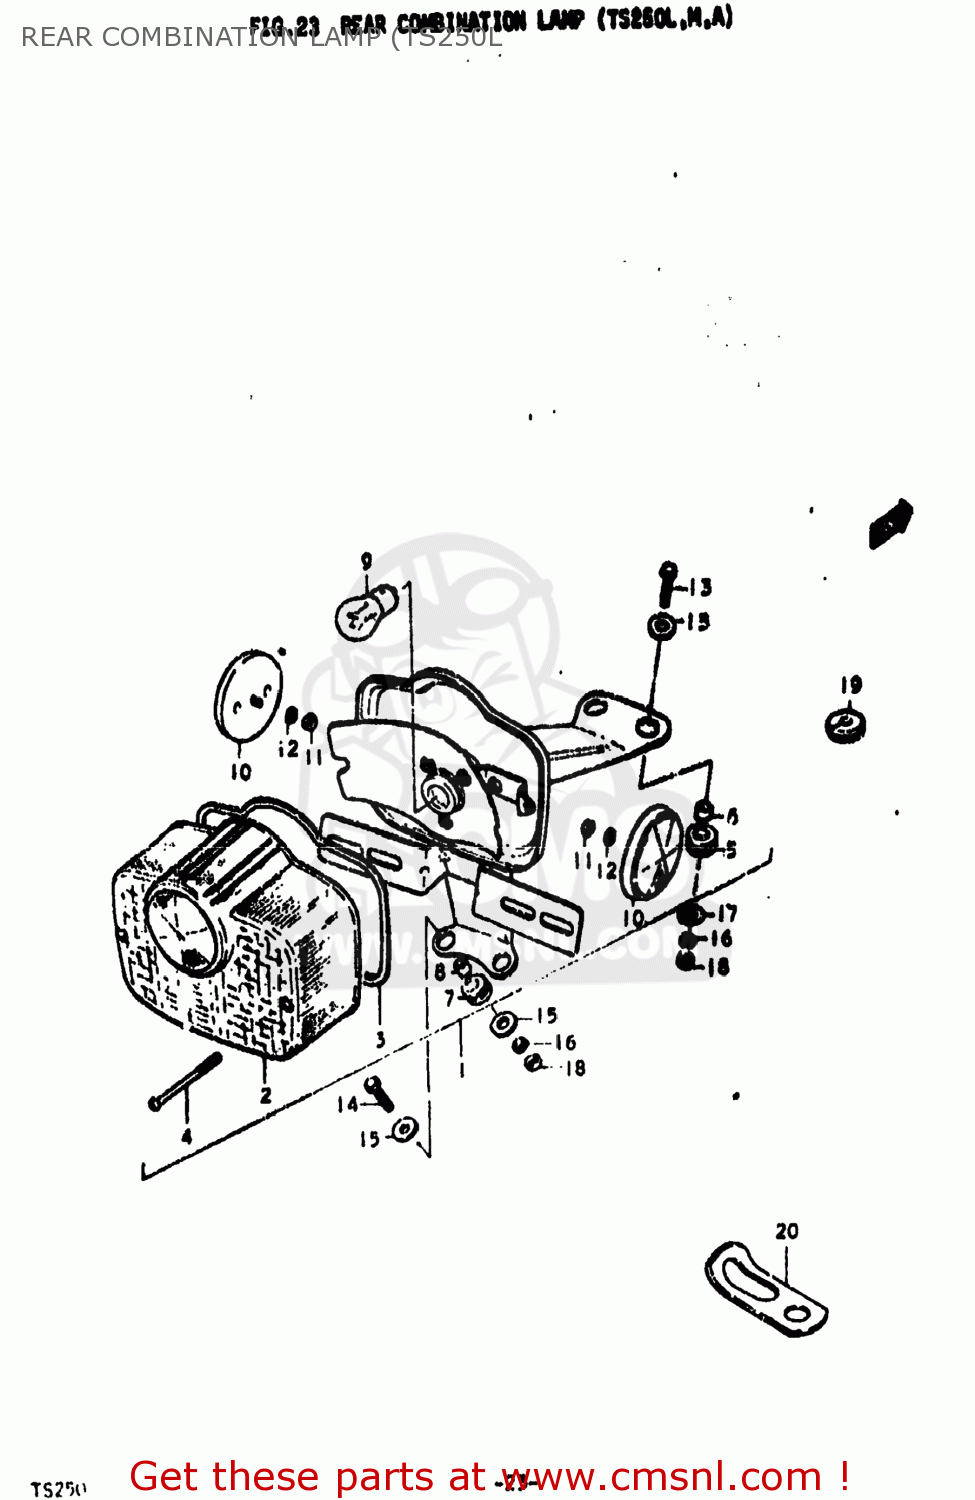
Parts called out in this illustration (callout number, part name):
1	LAMP ASSEMBLY,REAR COMBINATION
2	LENS,REAR COMBINATION LAMP
3	GASKET (NAS)
4	SCREW
5	CUSHION
6	SPACER,REAR COMBINATION LAMP
7	CUSHION
8	SPACER,REAR COMBINATION LAMP
9	BULB(6V32/3CP,STANLEY)
10	REFLECTOR,REFLEX
11	NUT
12	LOCK WASHER
13	BOLT
14	BOLT
15	WASHER
16	LOCK WASHER
17	WASHER
18	NUT
19	GROMMET
20	CLAMP
